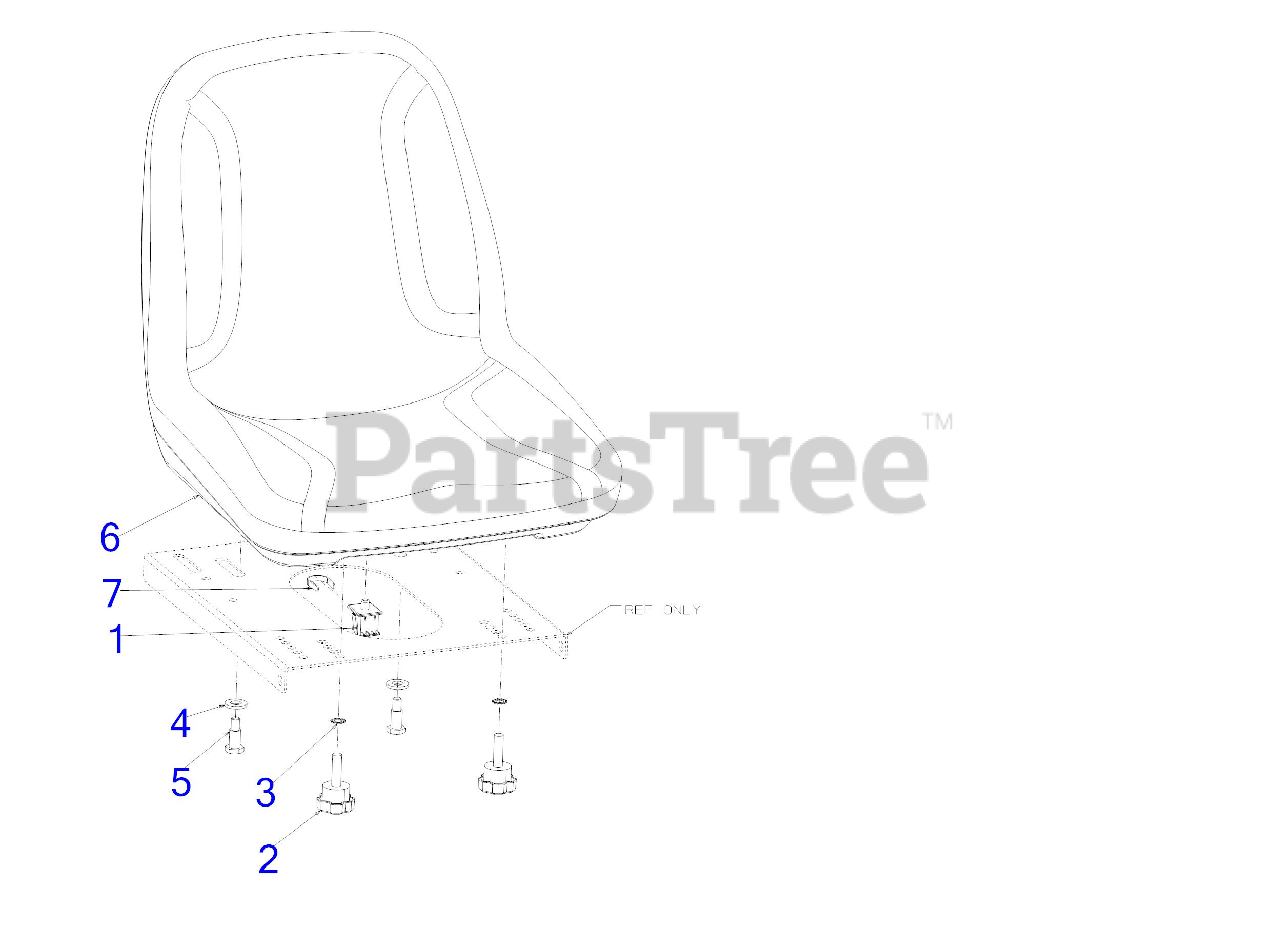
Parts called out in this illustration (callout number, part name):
1	SEAT SWITCH
2	SEAT ADJUST KNOB 3/8-16 X 1.50
3	LOCK WASHER 3/8
4	FLAT WASHER .510 x 1.000 x .125
5	SHOULDER SCREW .500
6	SEAT
7	RETAINING CLIP
